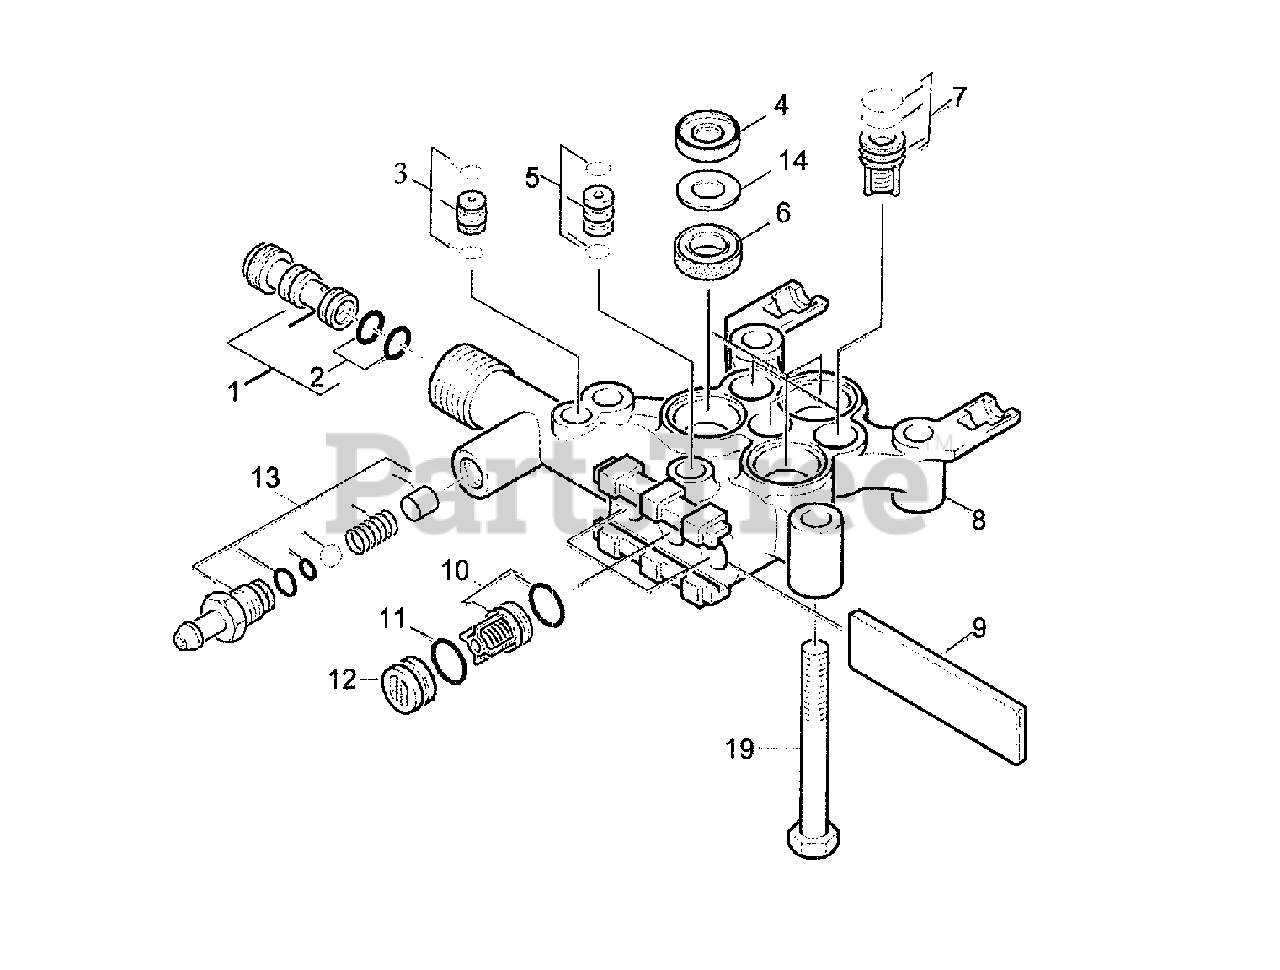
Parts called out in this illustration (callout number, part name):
1	Nozzle Insert
6	Grooved Ring
8	Cylinder Head
13	Rebuild Kit
